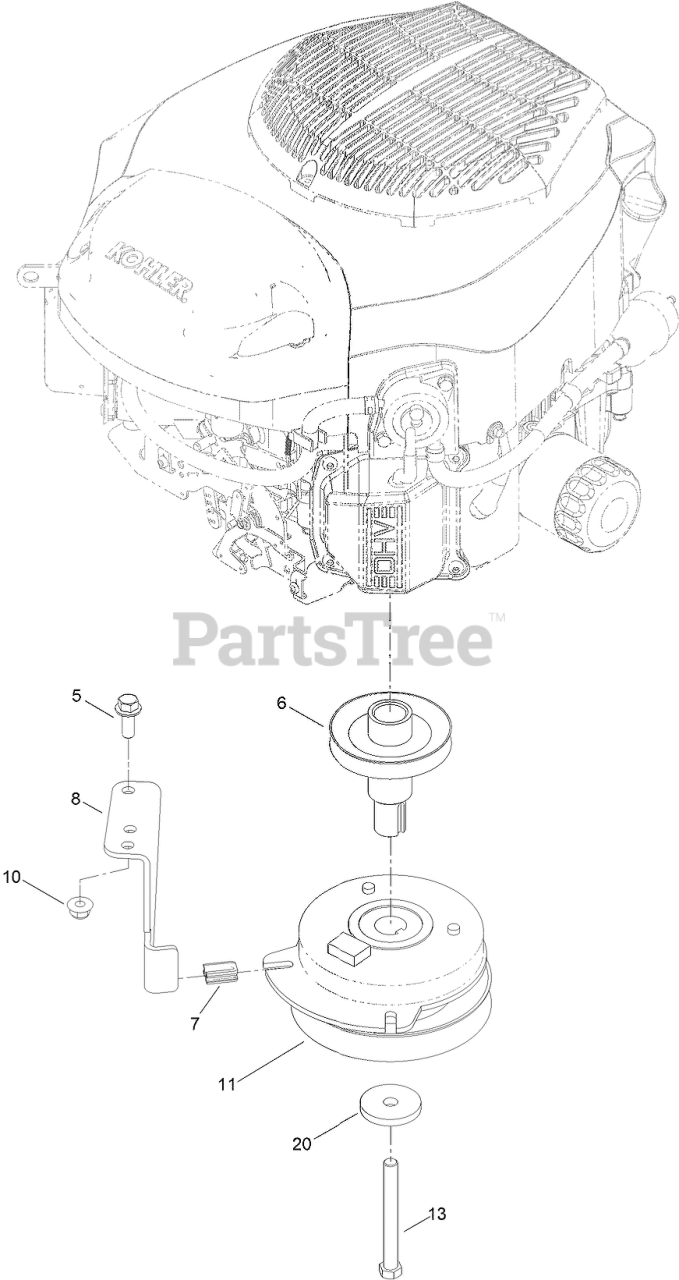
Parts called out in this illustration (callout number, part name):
5	SCREW-HHF
6	PULLEY-ENGINE
7	ISOLATOR-CLUTCH
8	STOP-CLUTCH
10	NUT-HF, NI
11	CLUTCH-PTO
13	SCREW-HH
20	WASHER-CLUTCH
